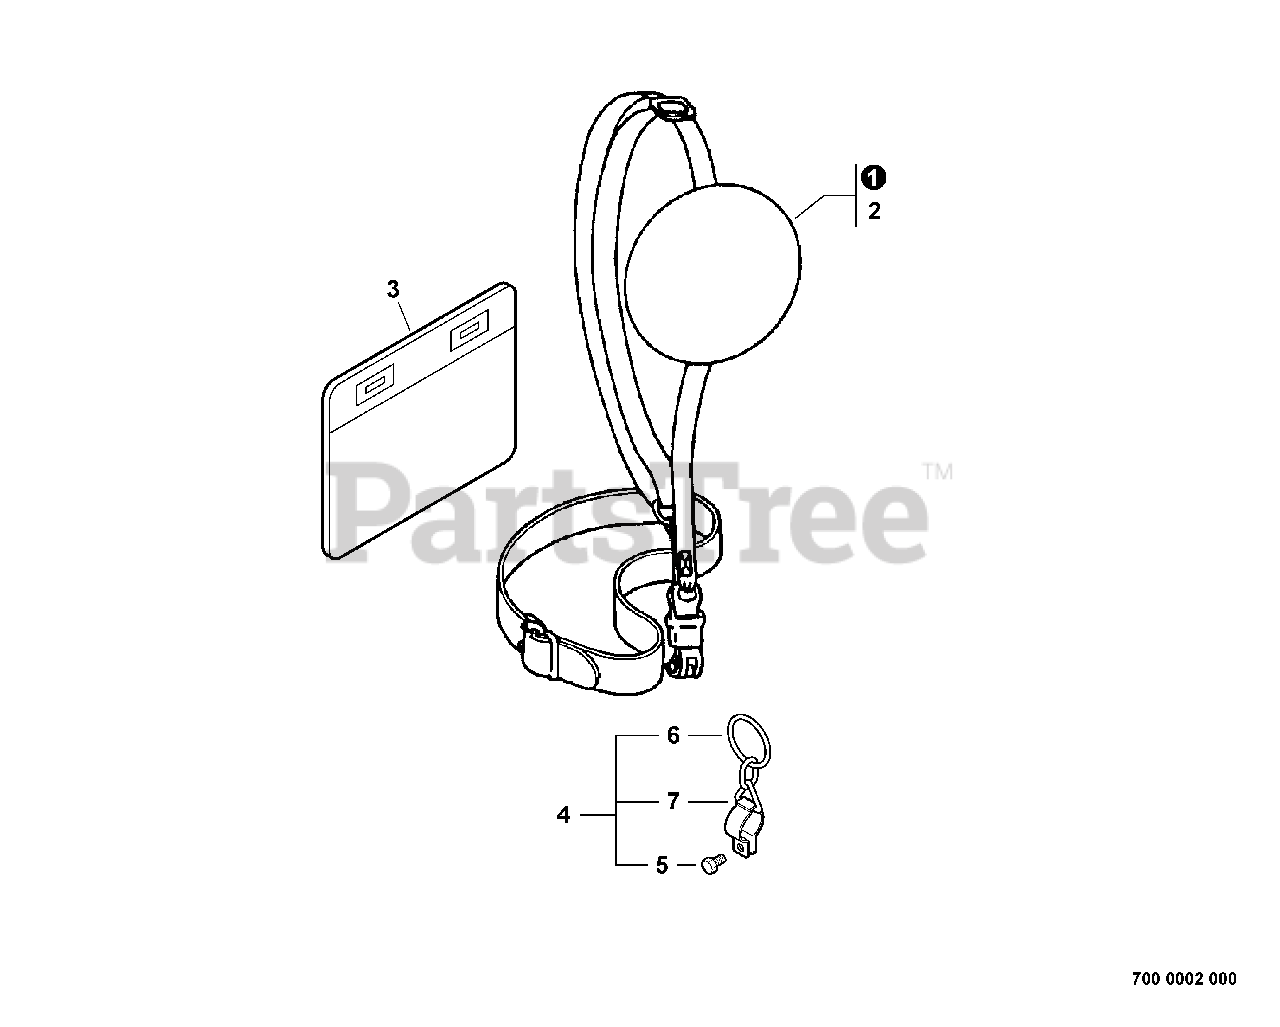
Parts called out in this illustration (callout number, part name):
1	HARNESS, SHOULDER
2	HARNESS, SHOULDER
3	PAD, HIP
4	HANGER SET, HARNESS
5	RING, HARNESS
6	HOOK
7	BOLT 5×12
